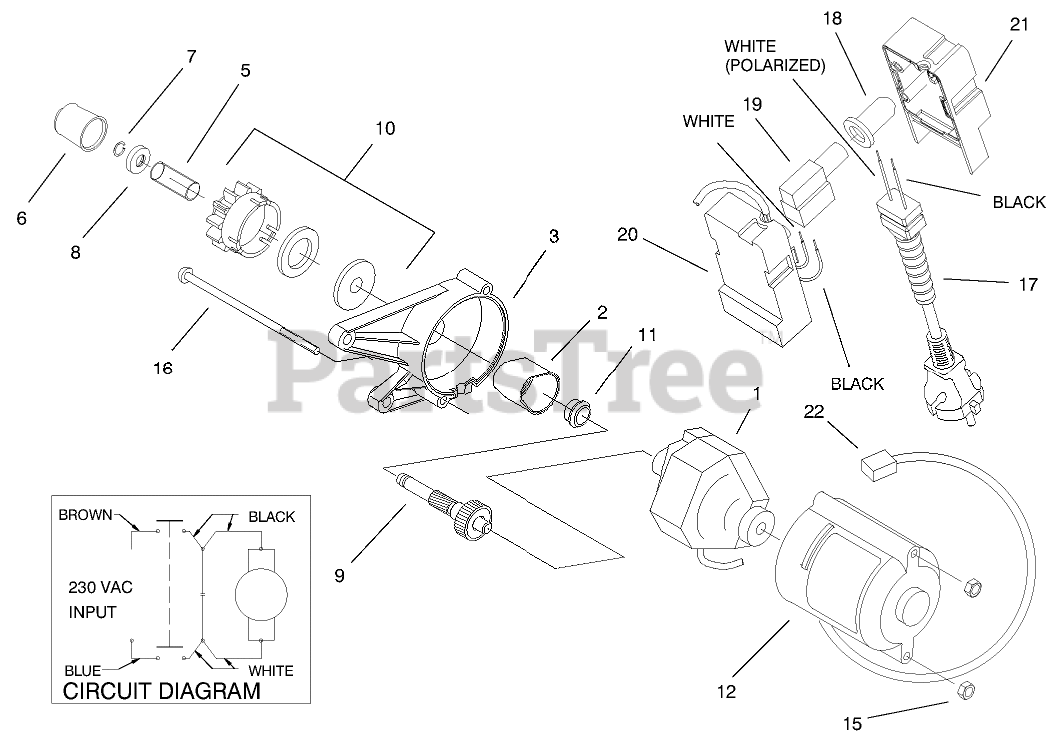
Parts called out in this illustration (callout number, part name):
1	MOTOR-STARTER
2	COVER-GEAR
3	Housing-Starter
5	SPRING
6	CAP-PINION
7	RING-LOCK
8	PINION STOP
9	Asm-shaft & Gear
10	PINION ASM
11	BUSHING
12	HOUSING COVER
15	NUT-LOCK, NI
17	PLUG - POWER
18	BOOT-SWITCH
19	SWITCH-STARTER
20	BASE - SWITCH HOUSING
21	Cap-Switch Hsg
22	TIE-CABLE
